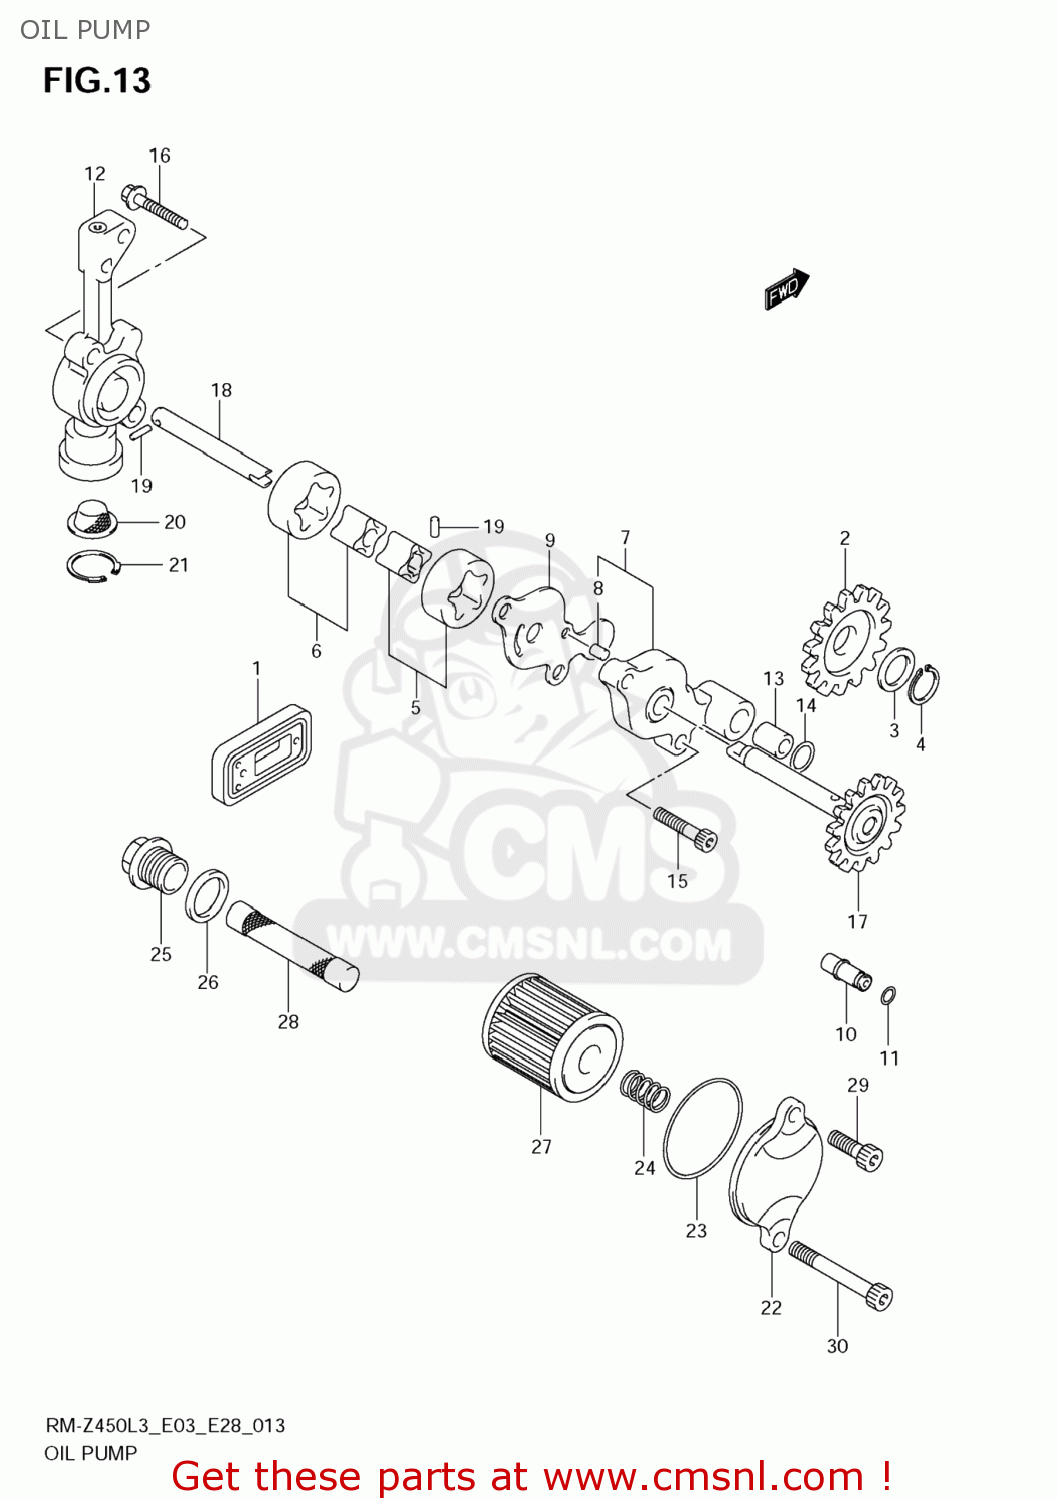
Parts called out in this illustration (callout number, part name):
1	VALVE ASSY,OIL REED
2	GEAR,OIL PUMP IDLE
3	SHIM(12X18X0.5)
4	CIRCLIP
5	ROTOR SET,OIL PUMP NO.1
6	ROTOR SET,OIL PUMP
7	COVER,OIL PUMP NO.1
8	PIN
9	PLATE,OIL PUMP NO.1
10	VALVE ASSY,OIL RELIEF
11	O RING(D:1.2,ID:4.7)
12	COVER,OIL PUMP NO.2
13	PIN
14	O RING(D:1.9,ID:8.6)
15	BOLT
16	BOLT(6X25)
17	SHAFT,OIL PUMP DRIVEN GEAR
18	SHAFT,OIL PUMP NO.2
19	PIN(2.5X11.8)
20	STRAINER,OIL PUMP NO.2
21	CIRCLIP
22	CAP,ENG OIL FILTER OUTER
23	O RING(D:2,ID:38.5)
24	SPRING
25	CAP,ENG OIL STRAINER
26	GASKET(16X22X2) (NAS)
27	FILTER ASSY,ENGINE OIL
28	STRAINER,ENGINE OIL
29	BOLT
30	BOLT
